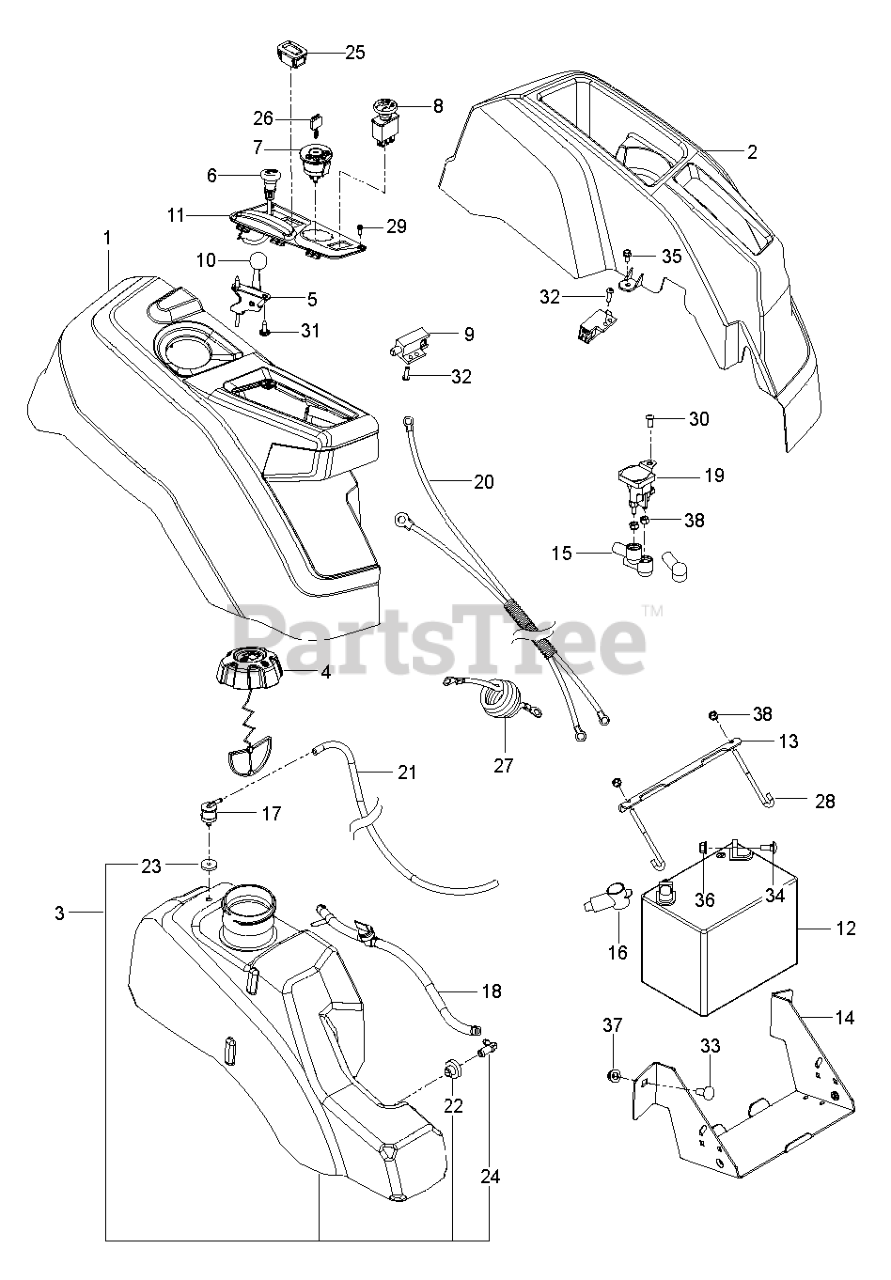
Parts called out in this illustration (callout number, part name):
1	CONSOLE.ASSY.RZ.REFRESH.RH
2	CONSOLE.LH.ASM
3	Tanks
3	TANK.ASM3"NECK.NOCAP.NOSHDRZ18
4	CAP ASSY FUEL 3" GRAY
4	FUEL CAP
5	THROTTLE CABLE
6	CHOKE.PUSH-IN.STYLE
7	RP IGNITION SWITCH
8	RP SWITCH.PTO.TERMINAL.STD.RED
9	SWITCH.INTLK.RZ.RFRSH.BUTTON
10	KNOB.ROUND.BALL.BLACK
11	CONTROL.PANEL.RZ.REFRESH.RH
12	BATTERY, 12 V 330 AMP
13	BRACKET.PNT.MOUNT.BATTERY.EDIP
14	BOX.PNT.BATTERY.RZ.EDIP
15	TERMINAL COVER
17	VALVE.FUEL.CHECK
18	FUEL.HOSE.SHUT.OFF.ASM.10".18"
19	SOLENOID.STARTER.BRASS.PLUNGER
20	HARNESS.BTTRY.CABLE.RZ.REFRESH
21	HOSE.3/16".VAPOR.LINE.50"LGTH
22	BUSHING OUTLET T
23	GROMMET.ROV.SENTEC
24	STEM FUEL TANK
25	GUAGE.SRVCMNDR.HRMTR.
26	KEY MLD GEN DELTA
27	CABLE BATTERY POS RZ
28	HOOK.J.BATTERY
29	SCREW 6-19X.437
30	SCR 1/4-20 X 5/8 BTN SKT HD ZD
31	SCREW.PAN.HEAD.#10
32	SCR #10-24 X .75 SKT HD BLK
33	RHSNB 3/8C X 1
34	RP BOLT 5/16-18 X3/4 ZN/YEL GR
35	SCREW
36	5/16-18 NYLOC FLANGE NUT
37	NUT 3/8-16 HEX FLG NYLOC ZD
38	NUT.1/4-20.HEX.NYLOC.ZD
